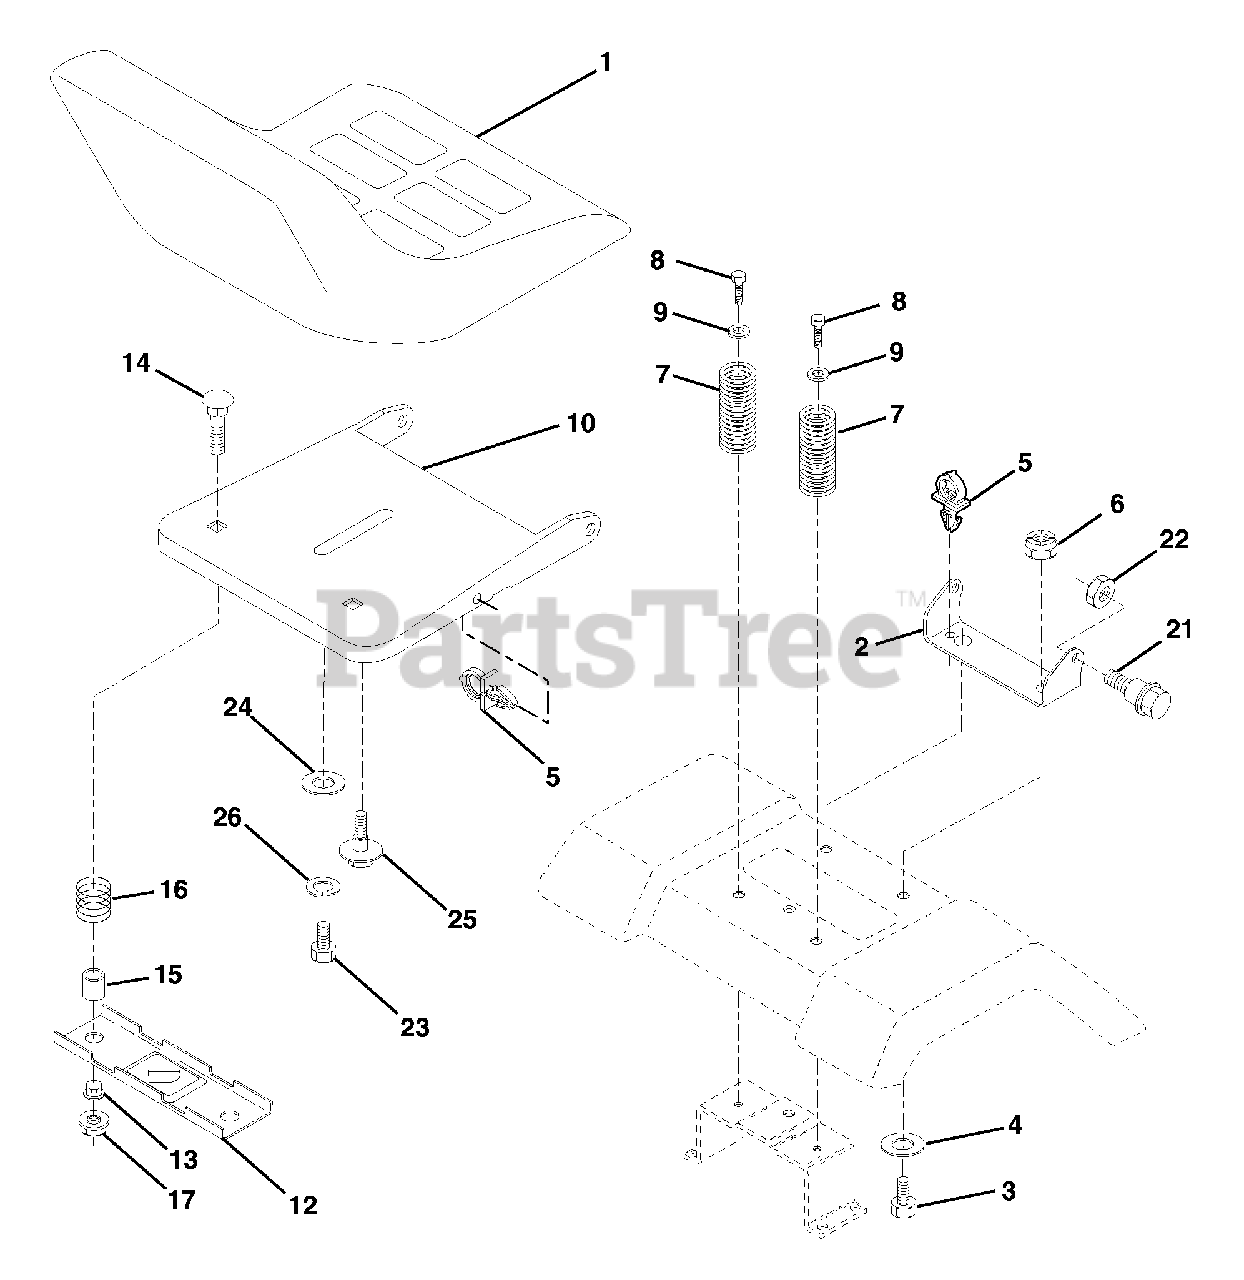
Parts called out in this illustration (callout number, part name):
1	Seat
2	Bracket Pnt Pivot Seat (blk)
3	Bolt 3/8-16 x 1
4	Washer 13/32 x 1 x 10 Ga.
5	Clip Push-In Hinged
6	Nut
7	Spring Seat Cprsn 2 250 Blk Zi
8	Screw 3/8-16 x 1.5
9	Washer 13/32 x 1 x 14 Ga.
10	Pan Pnt Seat
12	Bracket Pnt Mounting Switch
13	Bushing Snap Blk Nyl 50 Id
14	Bolt Rdhd Sht Nk 1/4-20 x 1-1/2
15	Spacer Split 28 x 96 Yel Zinc
16	Spring Cprsn 1 27 Blk Pnt
17	Nut Lock 1/4 Lge Flg Gr. 5 Zinc
21	Bolt Shoulder 5/16-18 unc Blkz-2A
22	Nut
23	Bolt Hex Black
24	Washer 17/32 x 1-3/16 x 12 Ga.
25	Bolt Shoulder 5/16-18 x 62
26	Lockwasher
